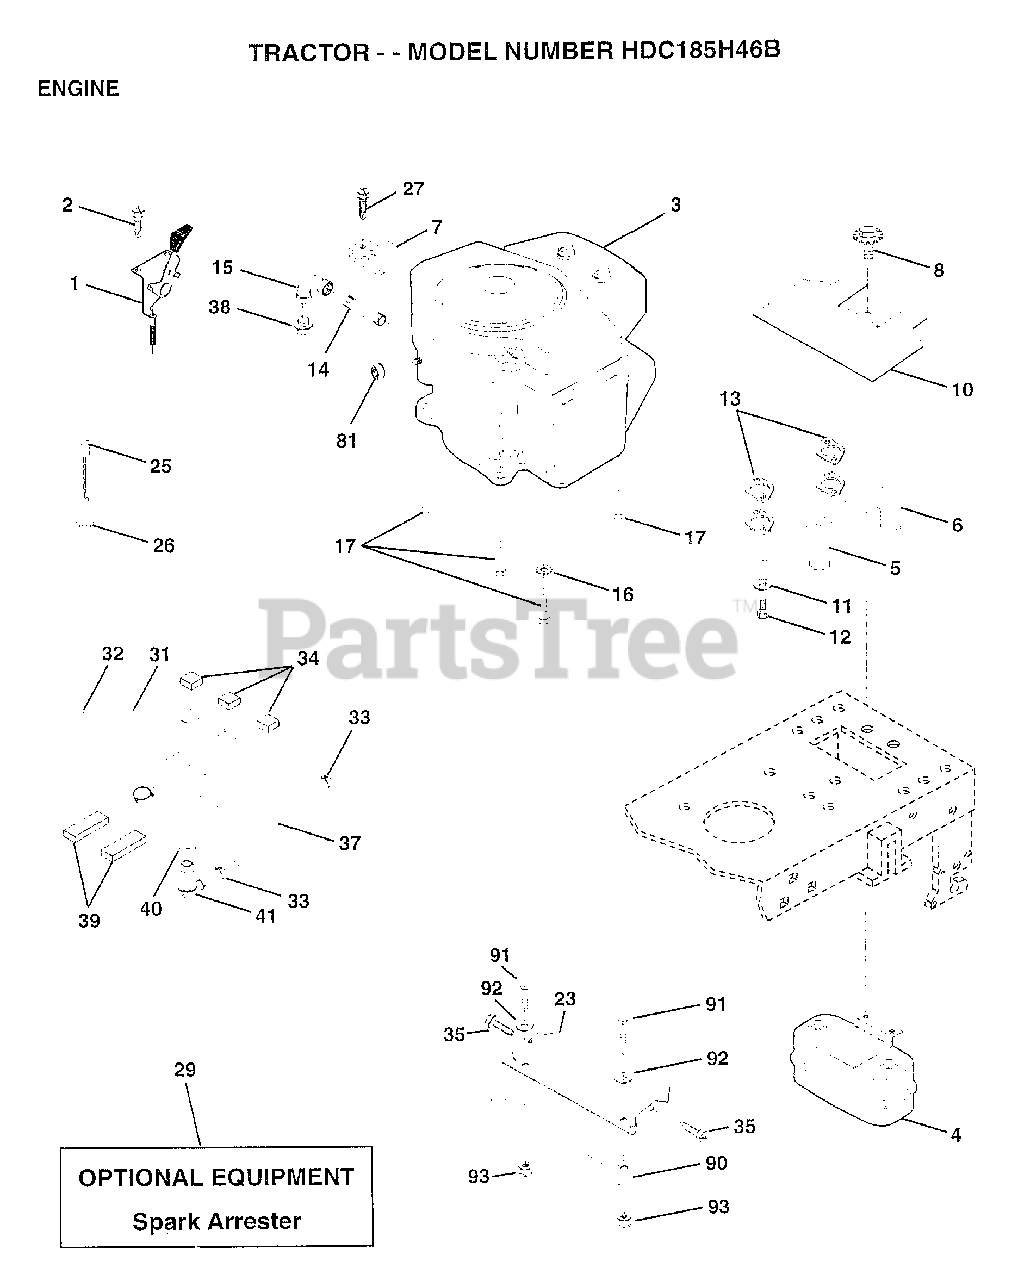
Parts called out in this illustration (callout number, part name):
1	CONTROL THRT 35.5
2	SCREW LT
4	MUFFLER.TW.LOTONE
5	EXHAUST.B&S.18.RH
6	EXHAUST.B&S.18.LH
7	CLAMP.TUBE.DBL.EN
8	BOLT.5/16-18.UNC
10	SHIELD.HEAT.
11	LOCKWASHER
13	GASKET MUFFLER
14	PIPE NIPPLE LT
15	ELBOW
16	LOCKWASHER
17	SCREW LT
23	SHIELD-HEAT
25	CONTROL.CHOKE.37
26	"NUT,KEPS 3/8-24IM"
27	"SCREW-TT,10-32 FL"
31	TANK FUEL REAR
32	CAP ASM FUEL
33	HOSE CLAMP
34	PAD-SPACER LT
35	SCREW
37	FUEL LINE T
39	PAD IDLER TI
40	BUSHING OUTLET T
41	STEM.TANK.FUEL
81	NUT
90	GUARD-DEBRIS
91	BOLT HXHD FIN
92	WASHER
